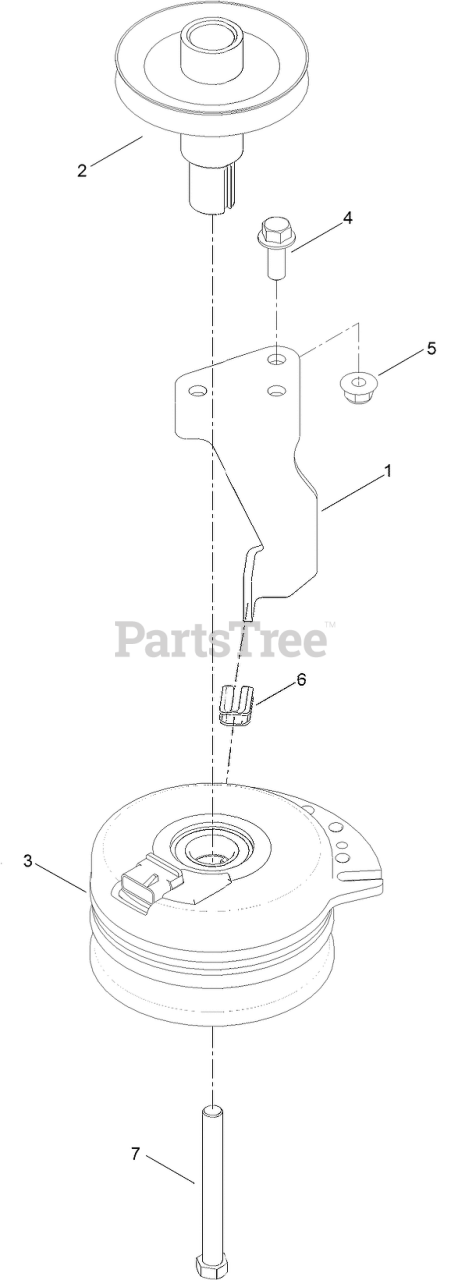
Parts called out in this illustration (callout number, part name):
1	STOP-CLUTCH (NARROW)
2	PULLEY-ENGINE
3	CLUTCH-ELECTRIC
4	SCREW-HHF
5	NUT-HF, NI
6	ISOLATOR-CLUTCH
7	SCREW-HH
